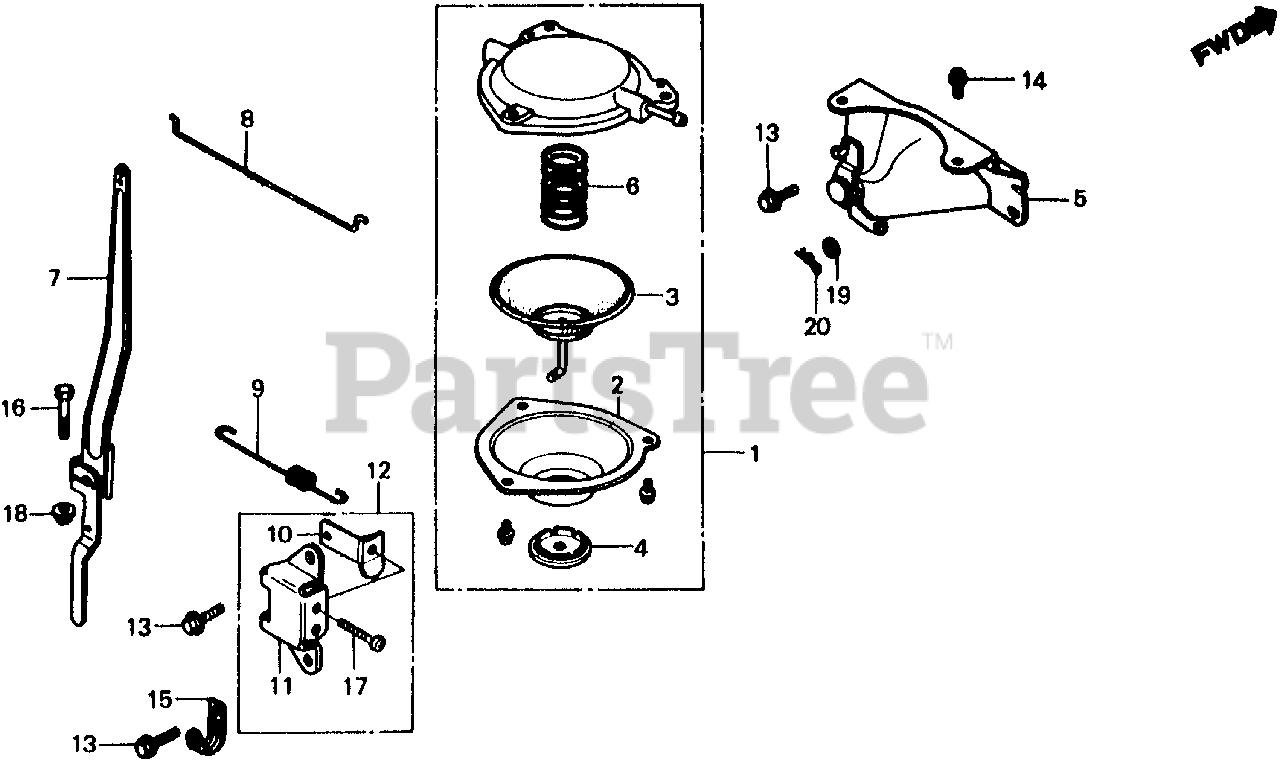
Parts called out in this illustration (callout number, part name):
1	DIAPHRAGM ASSY. (NOT AVAILABLE)
2	COVER, DIAPHRAGM
4	BUSH, DIAPHRAGM COVER
5	STAY, DIAPHRAGM (NOT AVAILABLE)
6	SPRING, COIL
7	ARM, GOVERNOR
8	ROD, GOVERNOR
9	SPRING, GOVERNOR
10	PLATE, CONTROL
11	BASE, CONTROL
12	LEVER, CONTROL
13	BOLT, FLANGE (6X12) (CT200)
14	SCREW-WASHER (5X8)
15	CLIP (2X50)
16	BOLT, GOVERNOR ARM
17	SCREW, PAN (6X28)
18	NUT, FLANGE (6MM)
19	WASHER, PLAIN (4MM)
20	PIN, LOCK (4MM)
